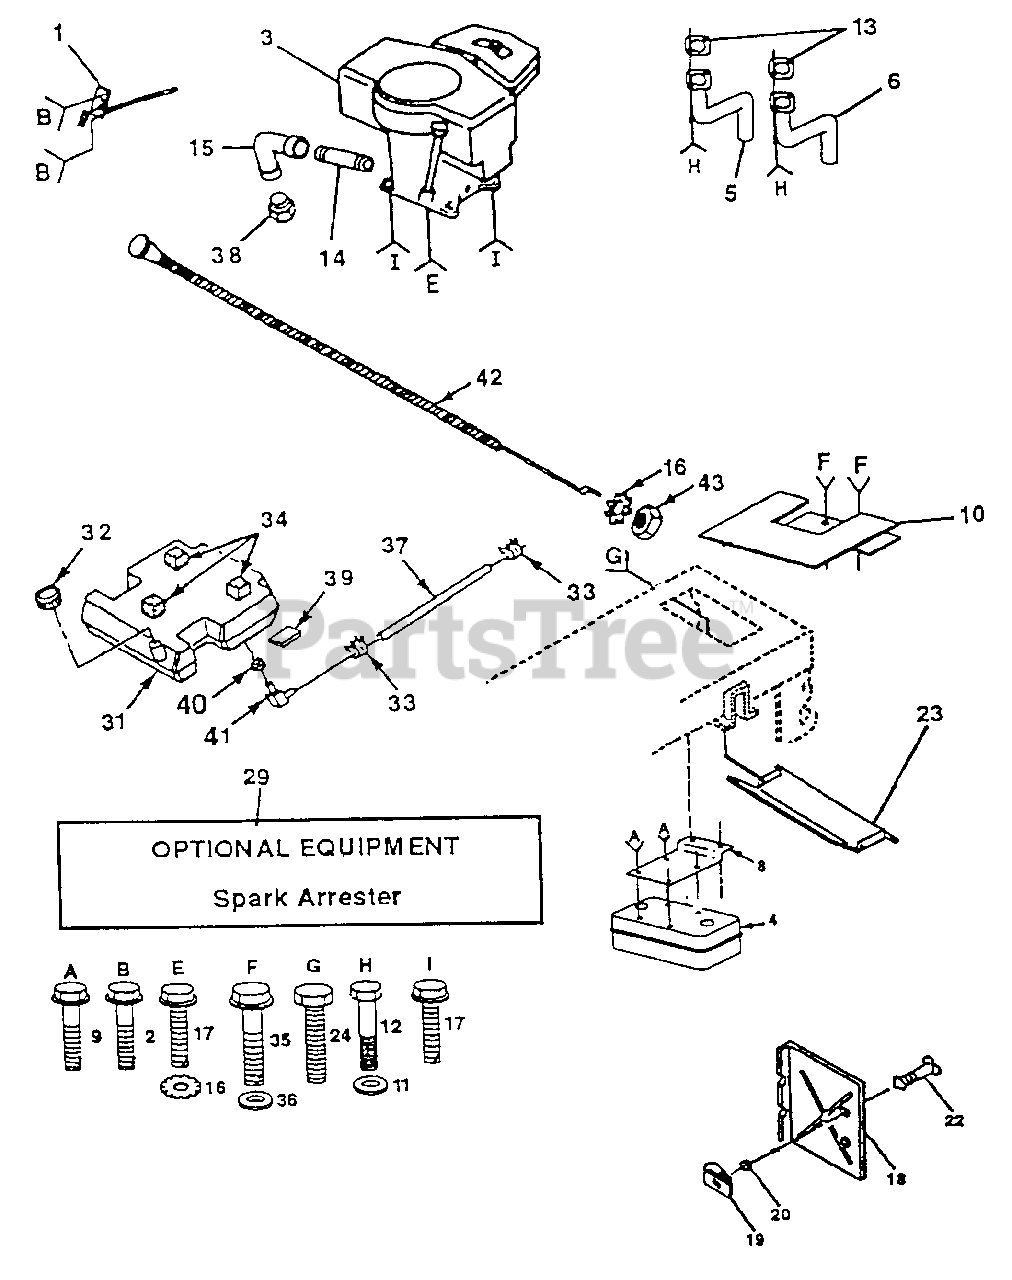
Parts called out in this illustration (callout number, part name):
1	Control PH, Blk Flg 37 88
2	Screw Hex Thd Cut 1/4-20x5/8 T
4	Muffler LT B&S
5	Tube Manifold LH
6	Tube Manifold RH
8	Bracket Muffler Mounting
9	Screw Hex Wsh Tnd Cut 1/4-20
10	Shield Heat LT
11	Washer Lock Hvy Hlcl 1/4
12	Bolt. Fin Hex 1/4-20 x 3/4
13	Muffler Gasket
14	Nipple Pipe 3/8 Npt X 4-1/2"
15	Elbow Std 90 Degree 3/8-18 Npt
16	Washer Lock Ext Tooth 3/8
17	Screw Thdrol 3/8-16 x 1-1/2
18	Shield Heat Electric
19	Receptacle 1/4 Turn
20	Retainer 1/4 Turn
22	Stud 1/4 Turn
23	Shield Heat Browning LT/YT
24	Screw Tap Hex #10-24unc X 1/2
29	Kit Spark Arrestor (Flat Scrn)
31	Tank Fuel 3 50 Rear
32	Cap Asm Fuel W/sym Vented
33	Clamp Hose Blk
34	Pad, Spacer
35	Screw Thdrol 5/16-18 x 3/4
36	Washer 13/32 x 1-1/4 x 14 Ga.
37	Line Fuel 54"
38	Plug Oil Drain
39	Pad, Idler
40	Bushing
41	Stem Tank Fuel
42	Choke Control
43	Nut, Fin Hex 3/8-24 Unf
